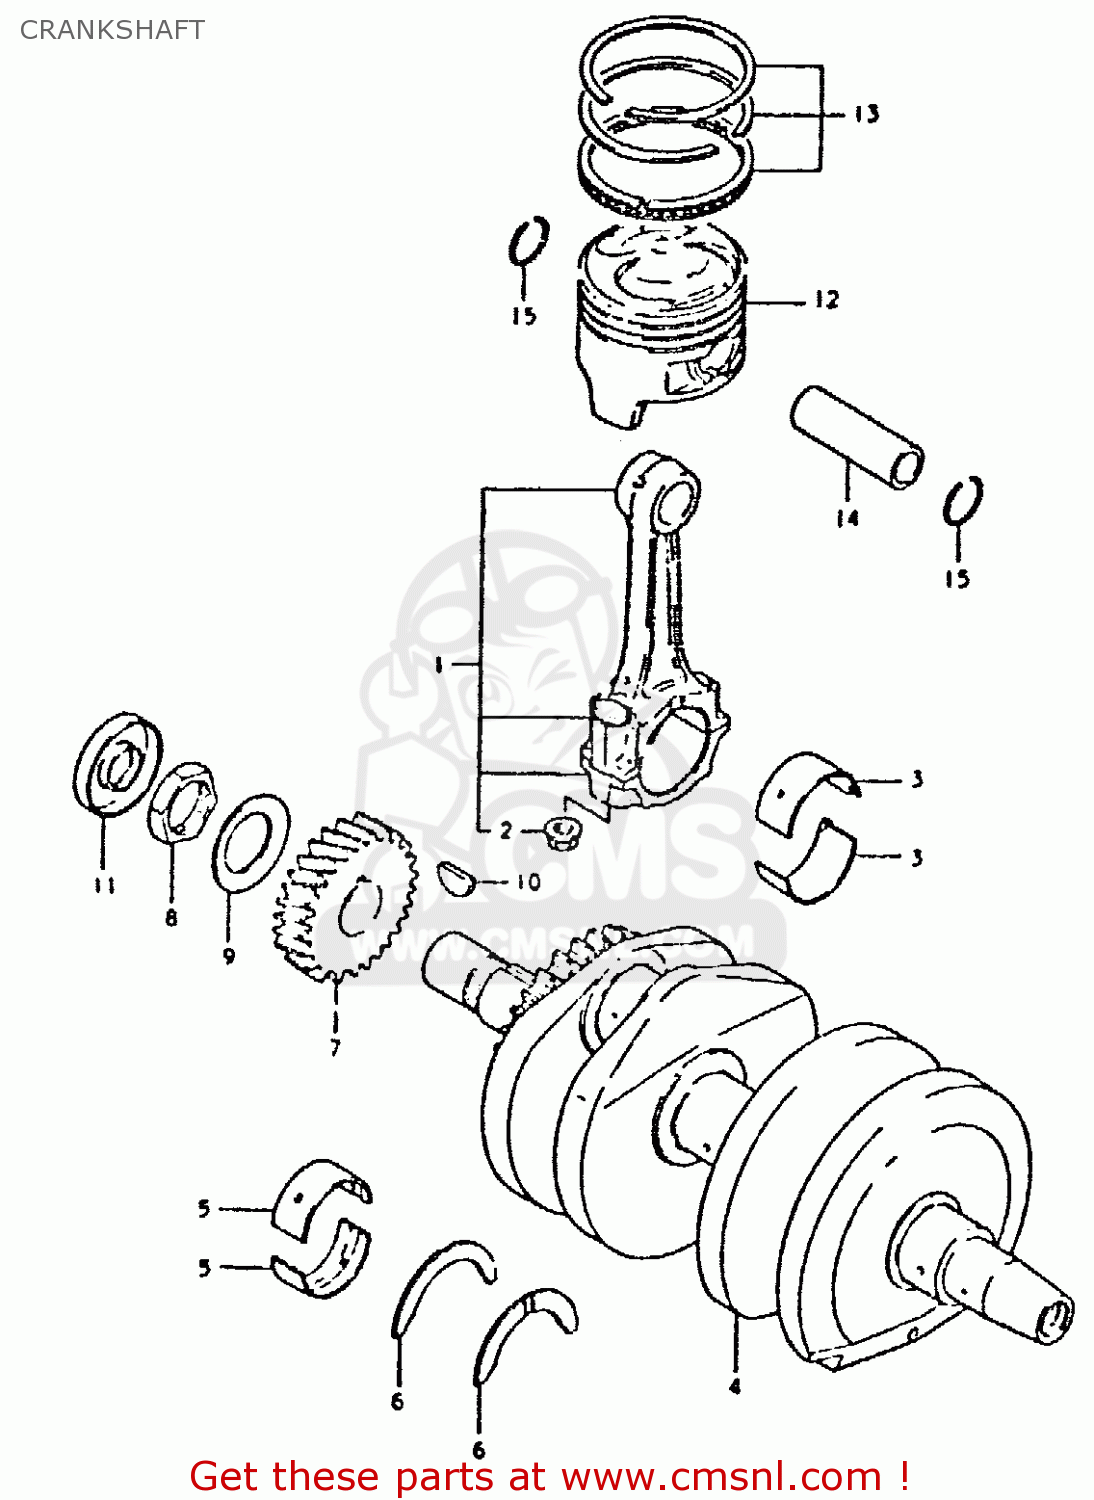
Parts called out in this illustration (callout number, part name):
1	ROD ASSEMBLY,CONNECTING
2	NUT
3	BEARING,CRANK PIN
4	CRANKSHAFT
5	METAL CRANKSHAFT
6	PLATE,CRANK THRUST
7	GEAR,PRIMARY DRIVE NO.28
8	NUT
9	WASHER
10	KEY
11	OIL SEAL
12	PISTON (STD)
13	RING SET,PISTON
14	PIN,PISTON
15	CIRCLIP,PISTON PIN
